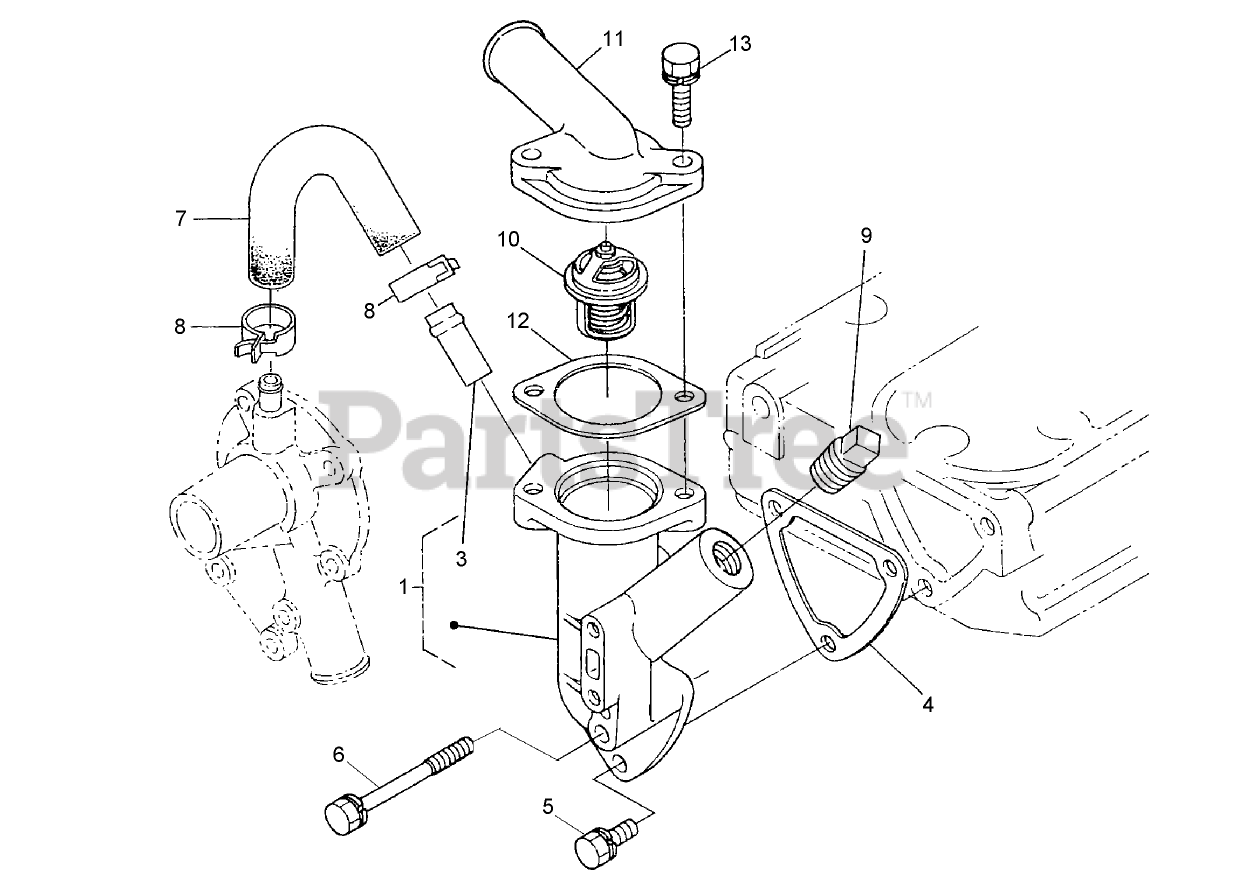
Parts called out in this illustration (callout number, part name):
1	WATER FLANGE ASM
3	PIPE-RETURN, WATER
4	GASKET-FLANGE, WATER
7	PIPE-RETURN, WATER
8	BAND-PIPE
10	THERMOSTAT ASM
11	COVER-THERMOSTAT
12	GASKET-THERMOSTAT
